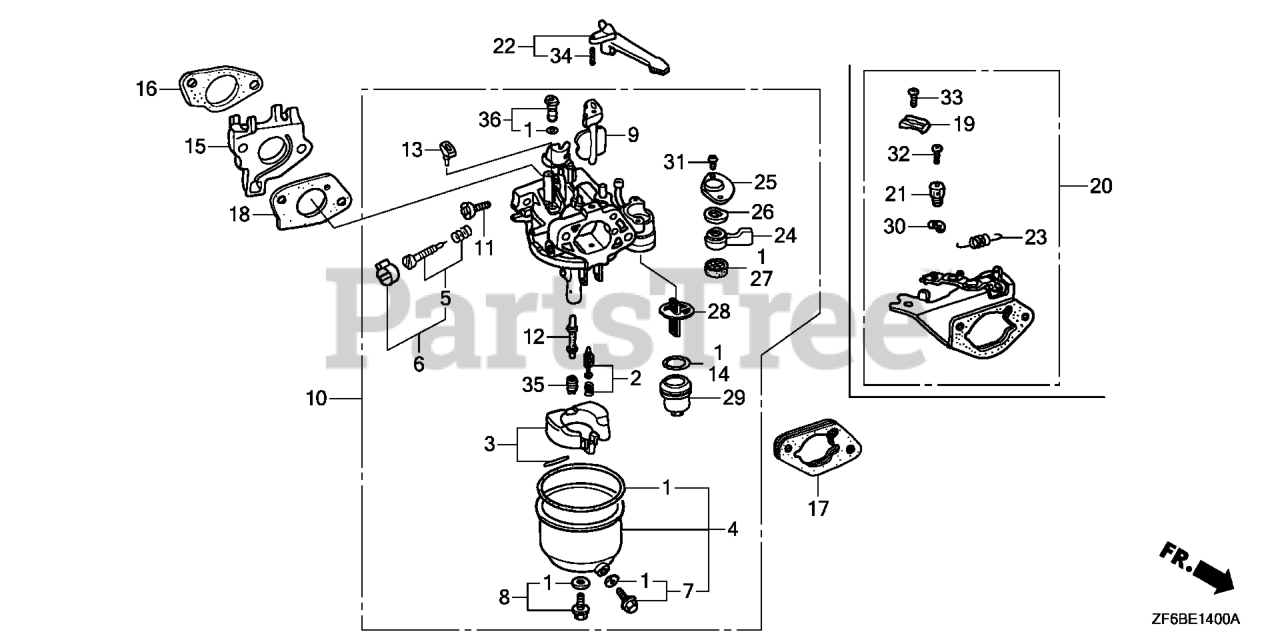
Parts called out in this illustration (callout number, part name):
1	GASKET SET (INCLUDE 16173-001-004) (INCLUDES 16173-001-004)
2	VALVE SET, FLOAT
3	FLOAT SET (CARBURETOR NO.)
4	CHAMBER SET, FLOAT
6	SCREW SET (Honda Code 4219879). (CARBURETOR NO.)
7	SCREW SET, DRAIN
8	SCREW SET (CARBURETOR NO.)
10	CARBURETOR ASSY. (BE88A A)
11	SCREW, THROTTLE STOP
12	NOZZLE, MAIN (CARBURETOR NO.)
13	COLLAR, SET
14	GASKET, FUEL STRAINER CUP
15	INSULATOR, CARBURETOR
16	GASKET, CARBURETOR INSULATOR
17	SPACER, CARBURETOR
18	GASKET, CARBURETOR
22	LEVER, CHOKE (STD)
24	LEVER, VALVE
25	PLATE, LEVER SETTING (CARBURETOR NO.)
26	SPRING, PETCOCK LEVER (CARBURETOR NO.)
27	GASKET, VALVE
28	FILTER, CUP (CARBURETOR NO.)
29	CUP, FUEL STRAINER
31	SCREW, PAN (3X6)
34	PIN, SPRING (2X12)
35	JET, MAIN (#98) Use from Engine SN BE87A A to BE87A A.
35	JET, MAIN (#102) (ADVENTURE GREEN) (CARBURETOR NO.)
35	JET, MAIN (#105) Use from Engine SN BE87H A.
36	JET SET, PILOT (#38)
